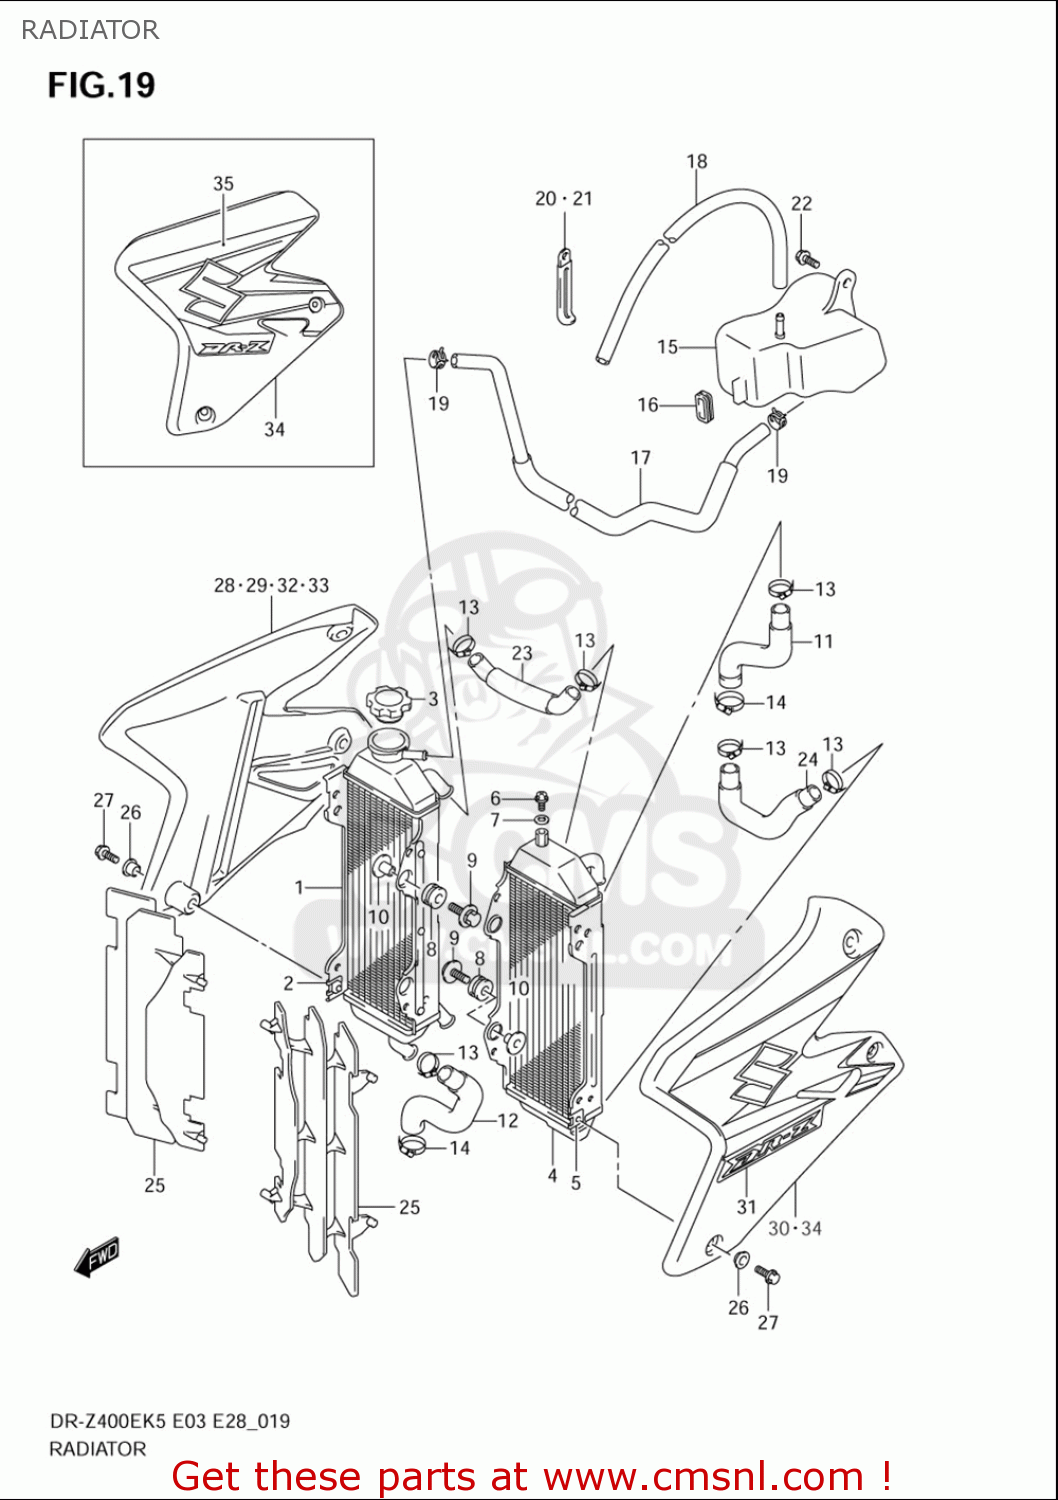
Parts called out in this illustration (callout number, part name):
1	RADIATOR,WATER,R
2	NUT
3	CAP,RADIATOR
4	RADIATOR,WATER,L
5	NUT
6	UNION BOLT,AIR VENT
7	GASKET(6.4X11.5X0.8) (NAS)
8	CUSHION,RADIATOR LWR
9	BOLT(6X25)
10	SPACER(6.5X10.5X14.1)
11	HOSE,RADIATOR INLET
12	HOSE,RADIATOR OUTLET
13	CLAMP
14	CLAMP
15	TANK,RESERVOIR
16	CUSHION,RESERVOIR TANK
17	HOSE,RESERVOIR TANK INLET
18	HOSE(5X9X2000)
19	CLIP
20	CLAMP(L:45 T:0.6)
21	CLAMP(L:65)
22	BOLT
23	HOSE,RADIATOR JOINT
24	HOSE,RADIATOR JOINT LWR
25	LOUVER,RADIATOR
26	WASHER
27	BOLT
28	COVER,RADIATOR,R(YELLOW)
29	TAPE,RADIATOR COVER,R
30	COVER,RADIATOR,L(YELLOW)
31	TAPE,RADIATOR COVER,L
32	COVER,RADIATOR,R(YELLOW)
33	TAPE,RADIATOR COVER,R
34	COVER,RADIATOR,L(YELLOW)
35	TAPE,RADIATOR COVER,L
